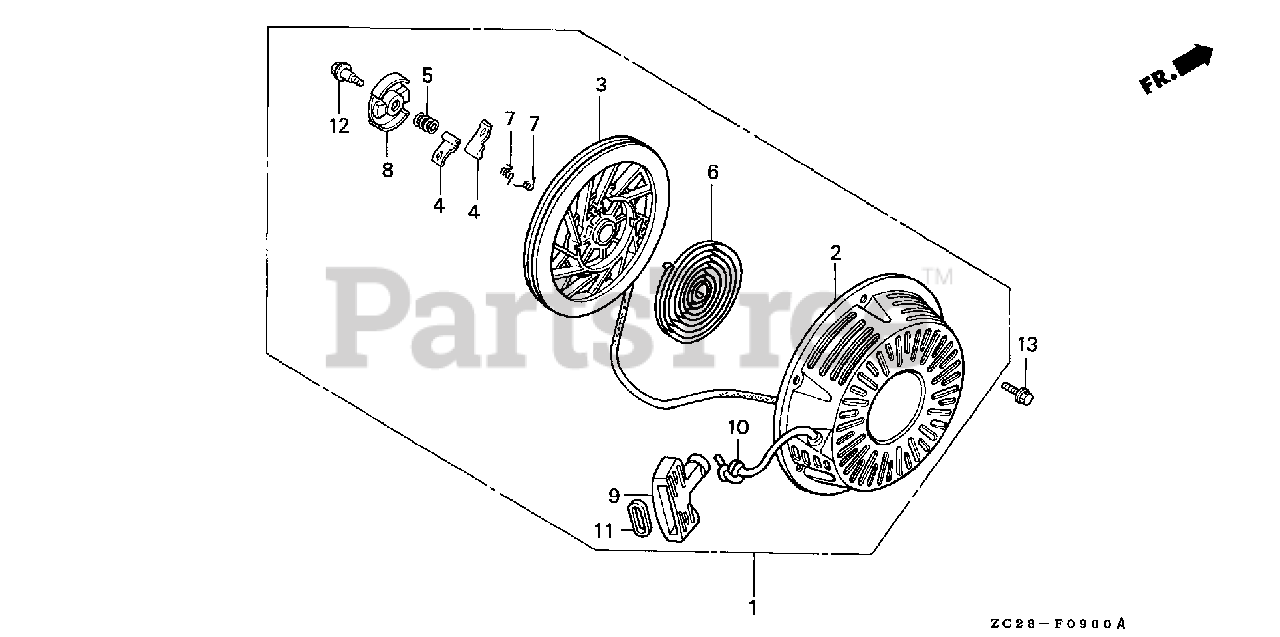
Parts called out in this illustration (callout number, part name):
1	STARTER ASSY., RECOIL *NH1* (BLACK)
2	CASE, RECOIL STARTER *NH1* (BLACK)
3	PULLEY, RECOIL STARTER
4	RATCHET, STARTER
5	SPRING, FRICTION
6	SPRING, STARTER RETURN
7	SPRING, RATCHET
8	RETAINER, SPRING
9	GRIP, STARTER
10	ROPE, RECOIL STARTER (#6X64") (N/A: USE P/N 08560-ZG921-11)
11	GRIP, REINFORCEMENT
12	SCREW, CENTER
13	BOLT, FLANGE (6X10)
